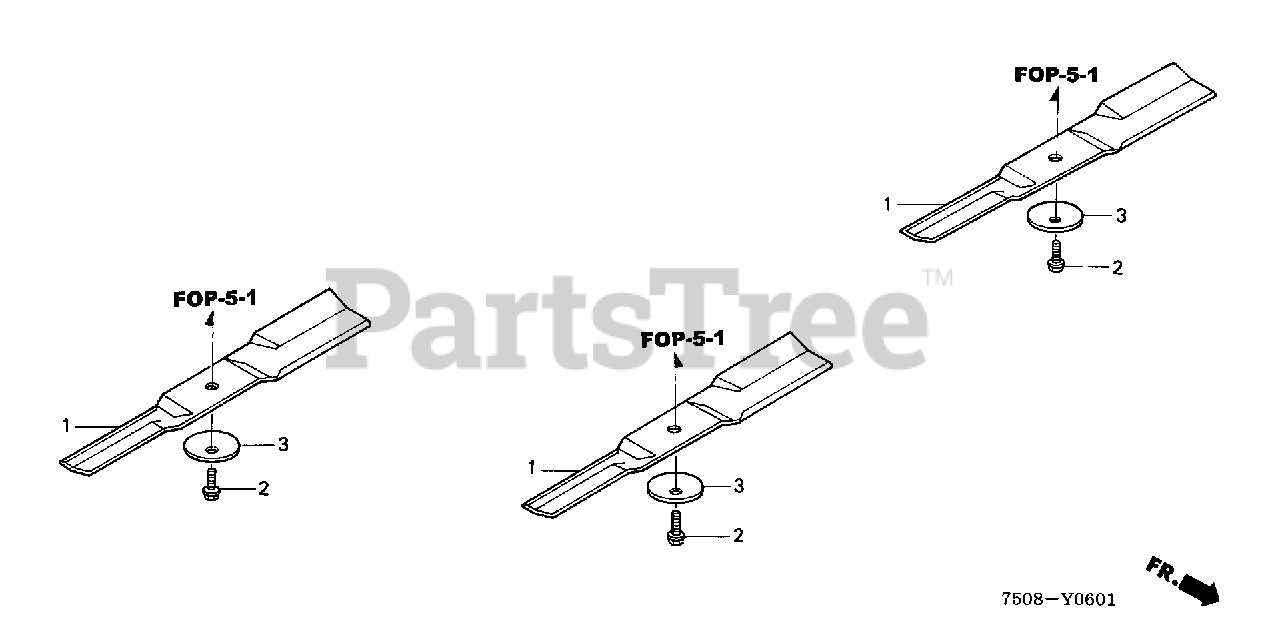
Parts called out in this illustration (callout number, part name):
1	BLADE, ROTARY
2	BOLT, BLADE HOLDER (10X28)
3	WASHER, BLADE
